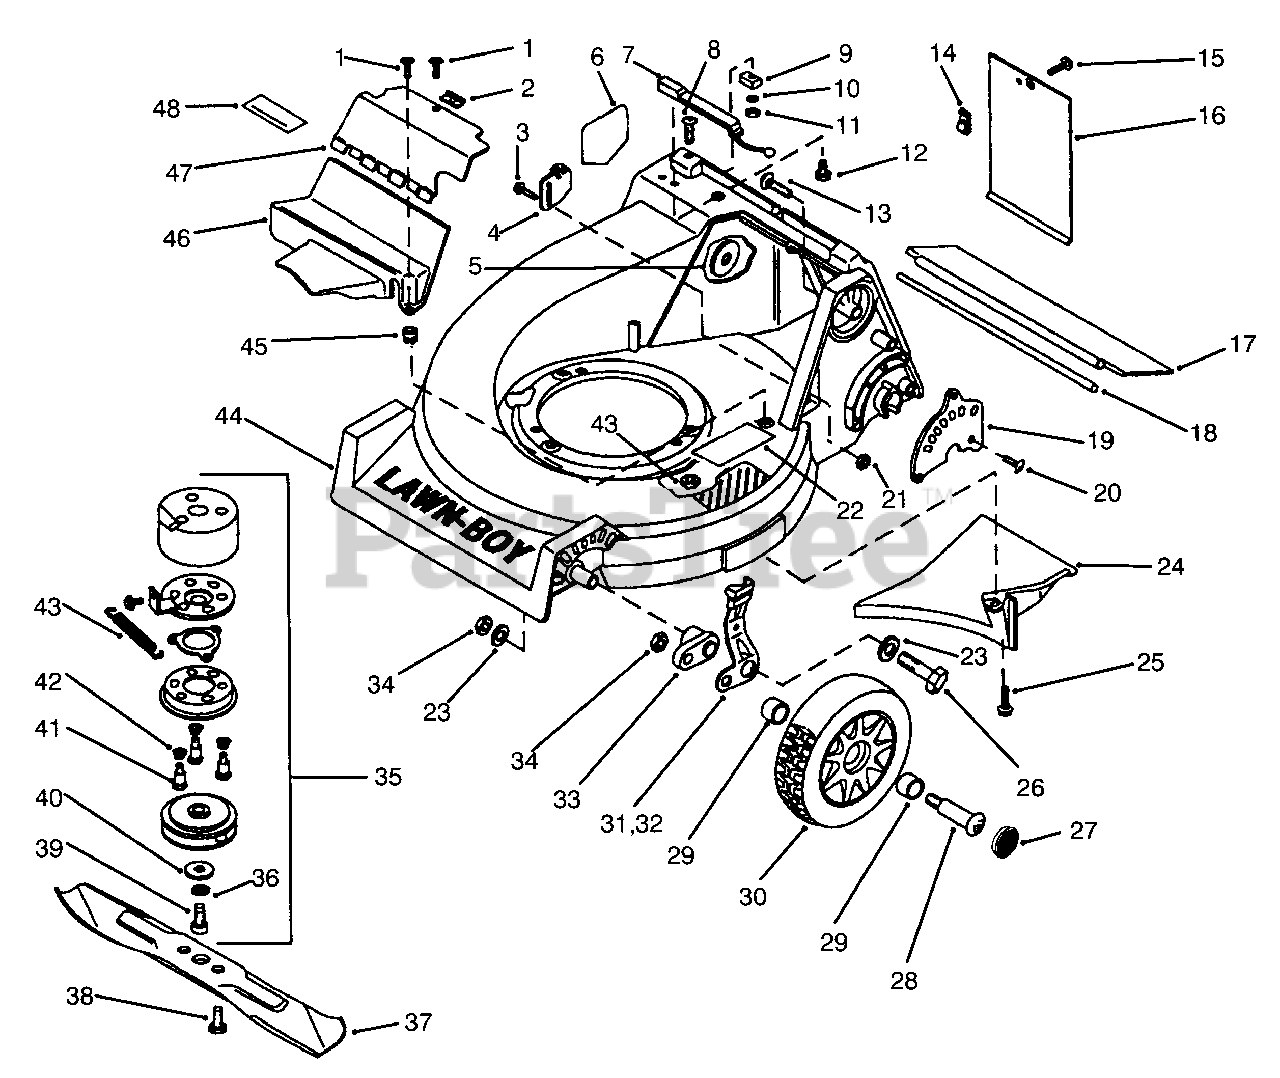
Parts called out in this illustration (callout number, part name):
2	Speednut
3	Screw-Anchor to Housing
4	Cable-Anchor
5	Washer-R.H. Handle Mtg.
6	Decal-Blade Warning
7	Assy.-Switch, Bag Lock
9	Assembly-Magnet
10	Lockwasher
13	Bolt-Handle Mounting
14	Speednut
16	Door-Access
17	Shield-Trailing
18	Rod-Trailing Shield
19	Plate-Height Adjustment
22	Decal-Foot Pad
28	Bolt-Wheel
29	Bushing-Wheel
30	Assembly Wheel & Tire (Incl. Ref. No. 29)
31	Assy.-Knob & Spring, L.H.
33	Arm-Front Height Adj.
35	Clutch & Brake Assy (Incl. Ref. No. 36, & 39-43)
36	Lockwasher
37	Blade-21"
38	Screw-Blade
42	Spring-Compression
43	Spring-Extension
44	Assembly-Housing (Incl. Ref. No. 5-6,13, & 24-25)
45	Grommet
46	Cover-Lower Drive
47	Cover-Upper Driver (Incl. Ref. No. 48)
48	Decal-Warning
